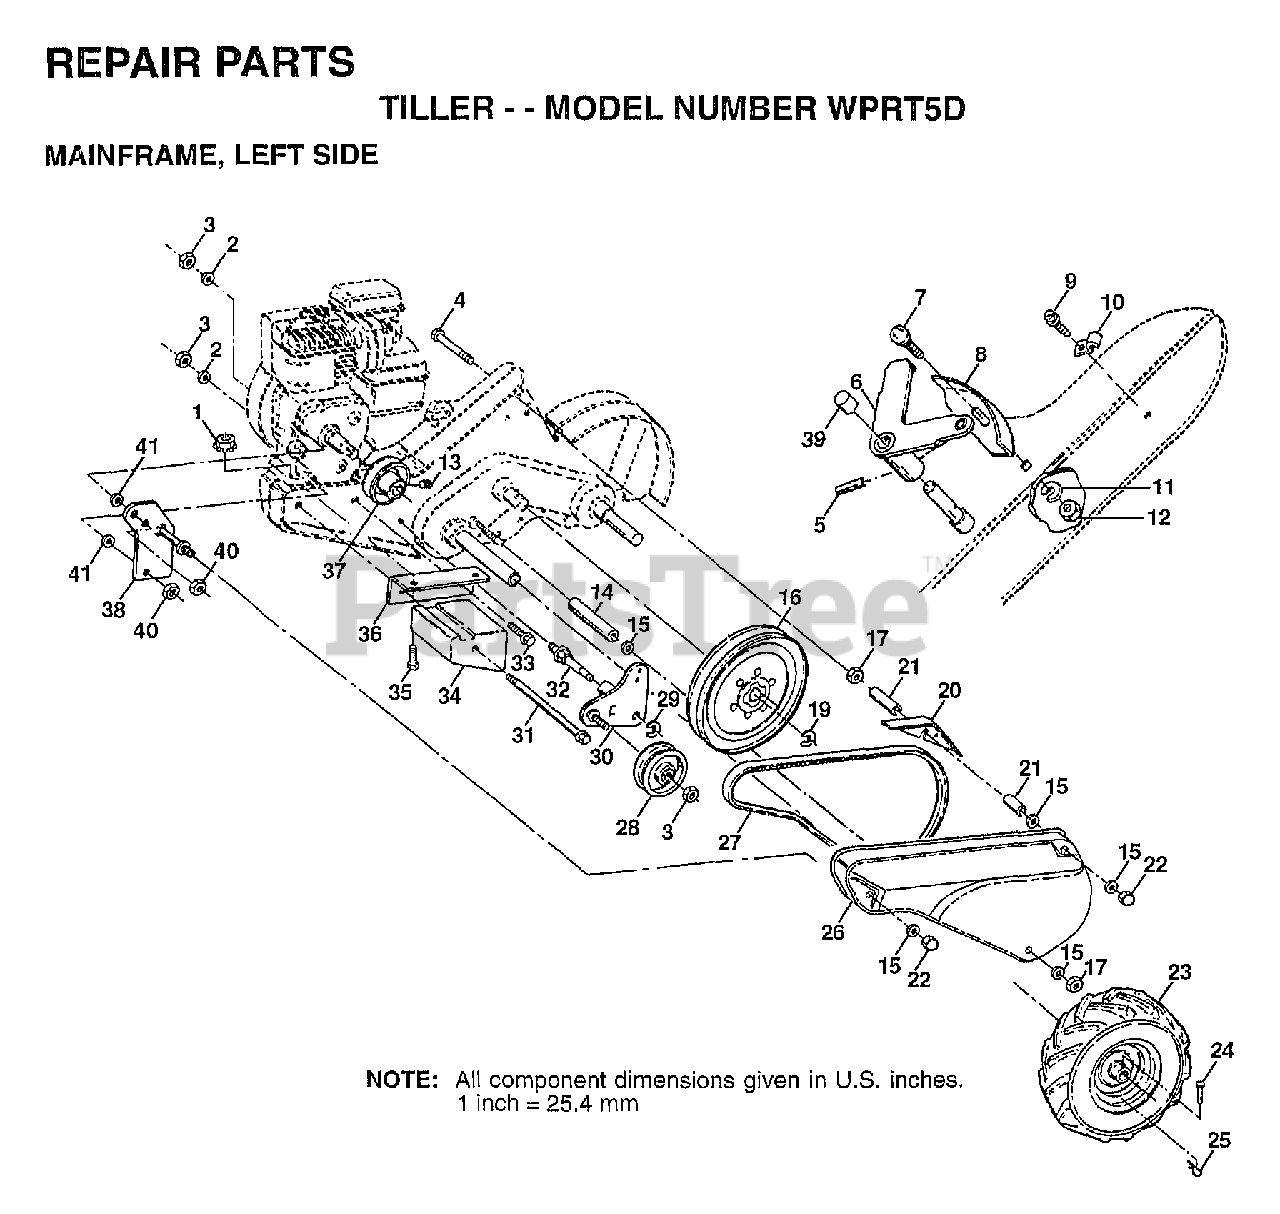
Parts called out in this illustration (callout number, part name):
2	LOCKWASHER
3	NUT.HEX.3/8-16UNC
4	BOLT TI
6	LEVER ASM CRT
7	BOLT
8	PANEL TI
10	CONDIUT CLIP T
11	LOCKWASHER
13	SET SCREW
14	SPACER
15	WASHER
16	SHEAVE.TRANS.
17	NUT.HEX.5/16-18
20	GUARD CRT
21	SPACER.SPLIT
22	NUT TI
23	TIRE TI
24	RIVET.DRILL.1.75
25	RETAINER M
27	BELT-V
28	PULLEY-IDLER TI
29	KLIP RING
31	BOLT CRT
32	SHIFT ARM CRT
33	BOLT
34	COUNTERWEIGHT CRT
35	BOLT
36	BRACKET LH CRT
37	ENGINE PULLEY
39	CAP PLUNGER BLACK
40	NUT
41	WASHER
